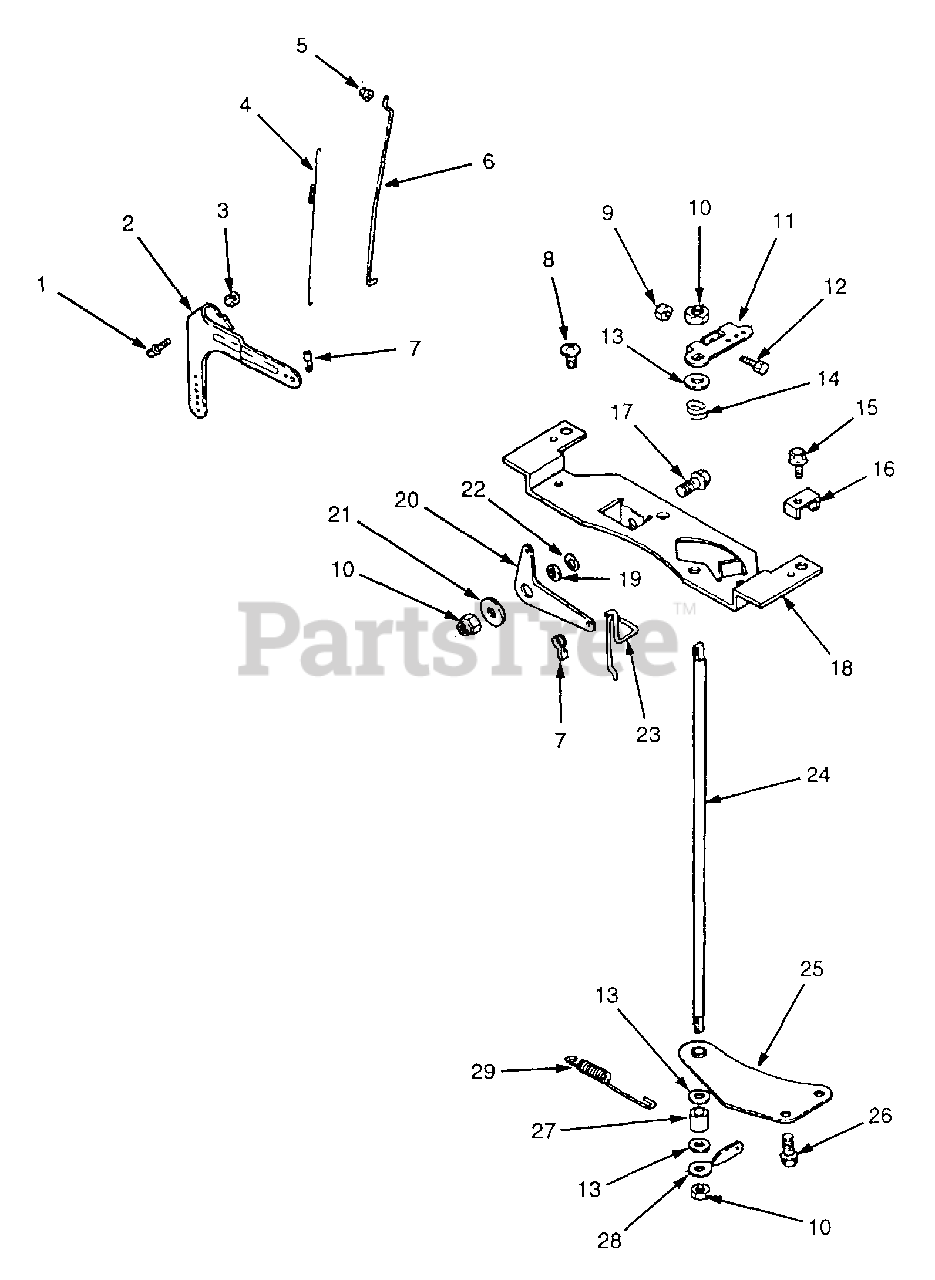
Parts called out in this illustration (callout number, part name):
1	Screw, Hex Flange, M6 x 1.0 x 25
2	Lever, Governor
3	Nut, Hex Flange, M6 x 1.0
4	Spring, Linkage
5	Bushing, Linkage Retaining
6	Linkage, Throttle
7	Bushing, Throttle Linkage
8	Screw, Phillips Hd 11-16 x 3/4
9	Nut, Hex, M4 x 0.7
10	Nut, Hex Lock, M6 x 1.0
11	Lever, Throttle Control
12	Screw, Hex Cap, M4 x 0.7 x 30
13	Washer, 1/4
14	Spring, Throttle Shaft
15	Screw, Hex Flange, M5 x 0.8 x 16
16	Clamp, Cable
17	Screw, Hex Flange, M6 x 1.0 x 16
18	Bracket, Control
20	Lever, Choke
21	Washer, 1/4
22	Washer, Spring, 3/8
23	Linkage, Choke
24	Shaft, Throttle
25	Bracket, Throttle Shaft
26	Screw, Hex Flange, M6 x 1.0 x 16
28	Lever, Throttle Control
29	Spring, Governor
